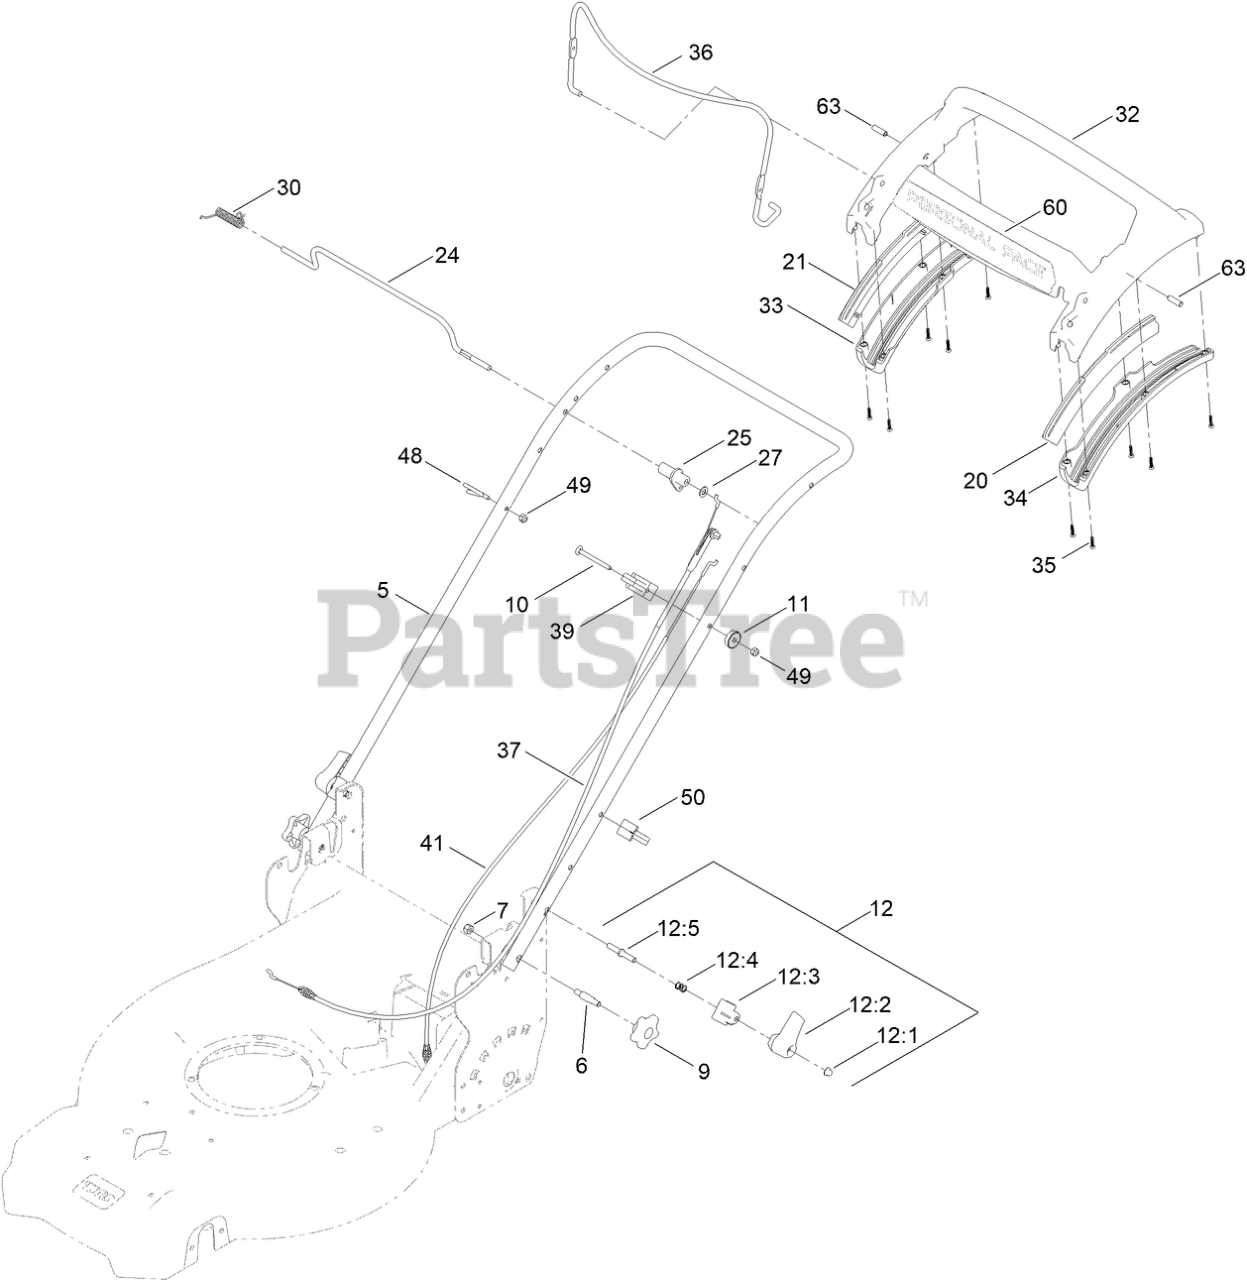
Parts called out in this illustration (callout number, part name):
5	HANDLE-CURVED
6	BOLT-SHOULDER, HANDLE
7	NUT-HEX
9	KNOB-HANDLE
10	SCREW-CARR
11	WASHER-CURVED
12	QUICK RELEASE ASM
12:1	NUT-PUSH
12:2	LEVER-RELEASE
12:3	ANCHOR-SPRING
12:4	SPRING-COMPRESSION
12:5	ROD-RELEASE
20	GUIDE-CURVED, LH (RWD)
21	GUIDE-CURVED, RH (RWD)
24	ROD-CONTROL, TRACTION
25	LEVER-TRACTION, RWD
27	WASHER-PLAIN
30	SPRING-TORSION
32	HANDLE-PERSONAL PACE, CURVED
33	BOTTOM-HANDLE, RH
34	BOTTOM-HANDLE, LH
35	SCREW-PPH
36	BAIL-BRAKE
37	CABLE-BRAKE, PP BS
39	ANCHOR-CABLE, RWD
41	CABLE-TRACTION, RWD (PP)
48	GUIDE-ROPE
49	NUT-HEX
50	GUIDE-CABLE
60	DECAL - ADS, HANDLE
63	PIN-HANDLE, PP
